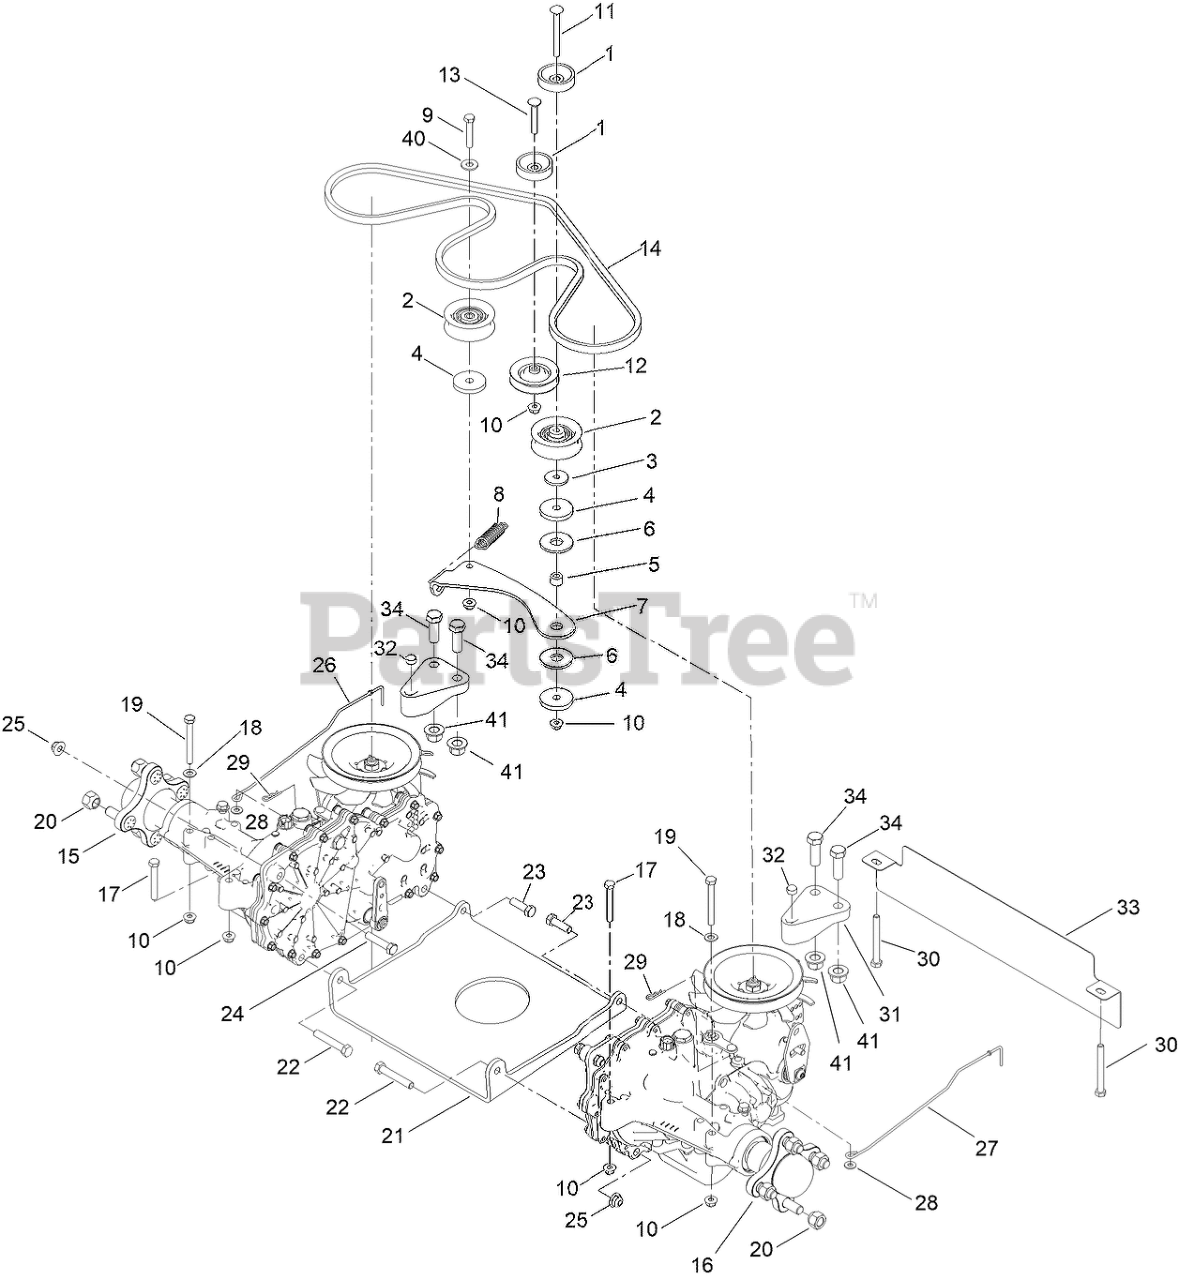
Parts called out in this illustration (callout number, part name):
1	SPACER
2	PULLEY-IDLER, FLAT
3	WASHER-FLAT
4	WASHER-PLAIN
5	BUSHING
6	WASHER-FRICTION, COMPOSITE
7	ARM-IDLER
8	SPRING-PEDAL, RETURN
9	SCREW-HH
10	NUT-HF
11	SCREW-CARR
12	PULLEY-IDLER
13	SCREW-CARR
14	V-BELT
15	RH HYDRO TRANSMISSION ASM
16	LH HYDRO TRANSMISSION ASM
17	SCREW-HH
18	WASHER-PLAIN
19	SCREW-HH
20	NUT-LUG
21	PLATE-CROSS, HYDRO
22	SCREW-HH
23	SCREW-HH
24	SCREW-HH
25	NUT-HF, NI
26	ROD-BYPASS, RH
27	ROD-BYPASS, LH
28	WASHER-FLAT
29	PIN-HAIR
30	SCREW-HH
31	SUPPORT-HYDRO, REAR
32	NUT-HEX
33	GUARD REAR, WIDE
34	SCREW-HH
40	WASHER-FLAT
41	NUT-HF
